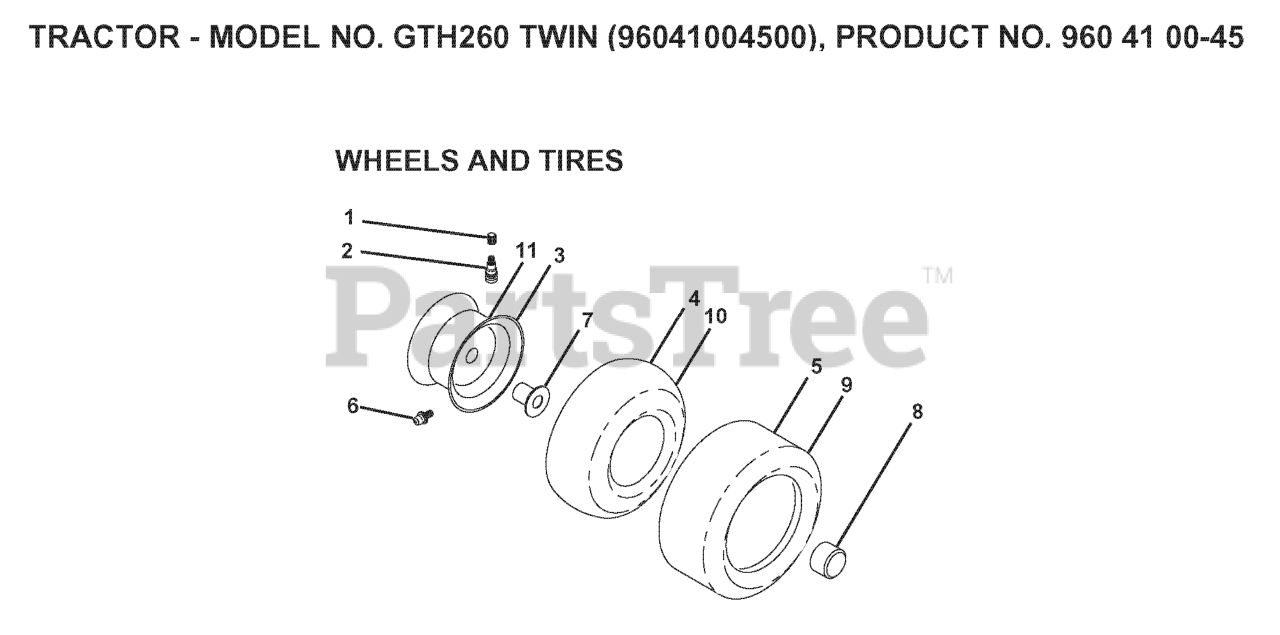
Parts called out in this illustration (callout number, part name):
2	VALVE STEM LT
3	RIM ASSEMBLY, FRONT
4	TUBE.5.3/4.5/6
5	TIRE HEAVY DUTY
6	FITTING LT
7	BEARING T
8	CAP, AXLE BLK
9	TIRE HEAVY DUTY
10	TUBE
11	RIM.ASM.12X7.REAR.SILVER
